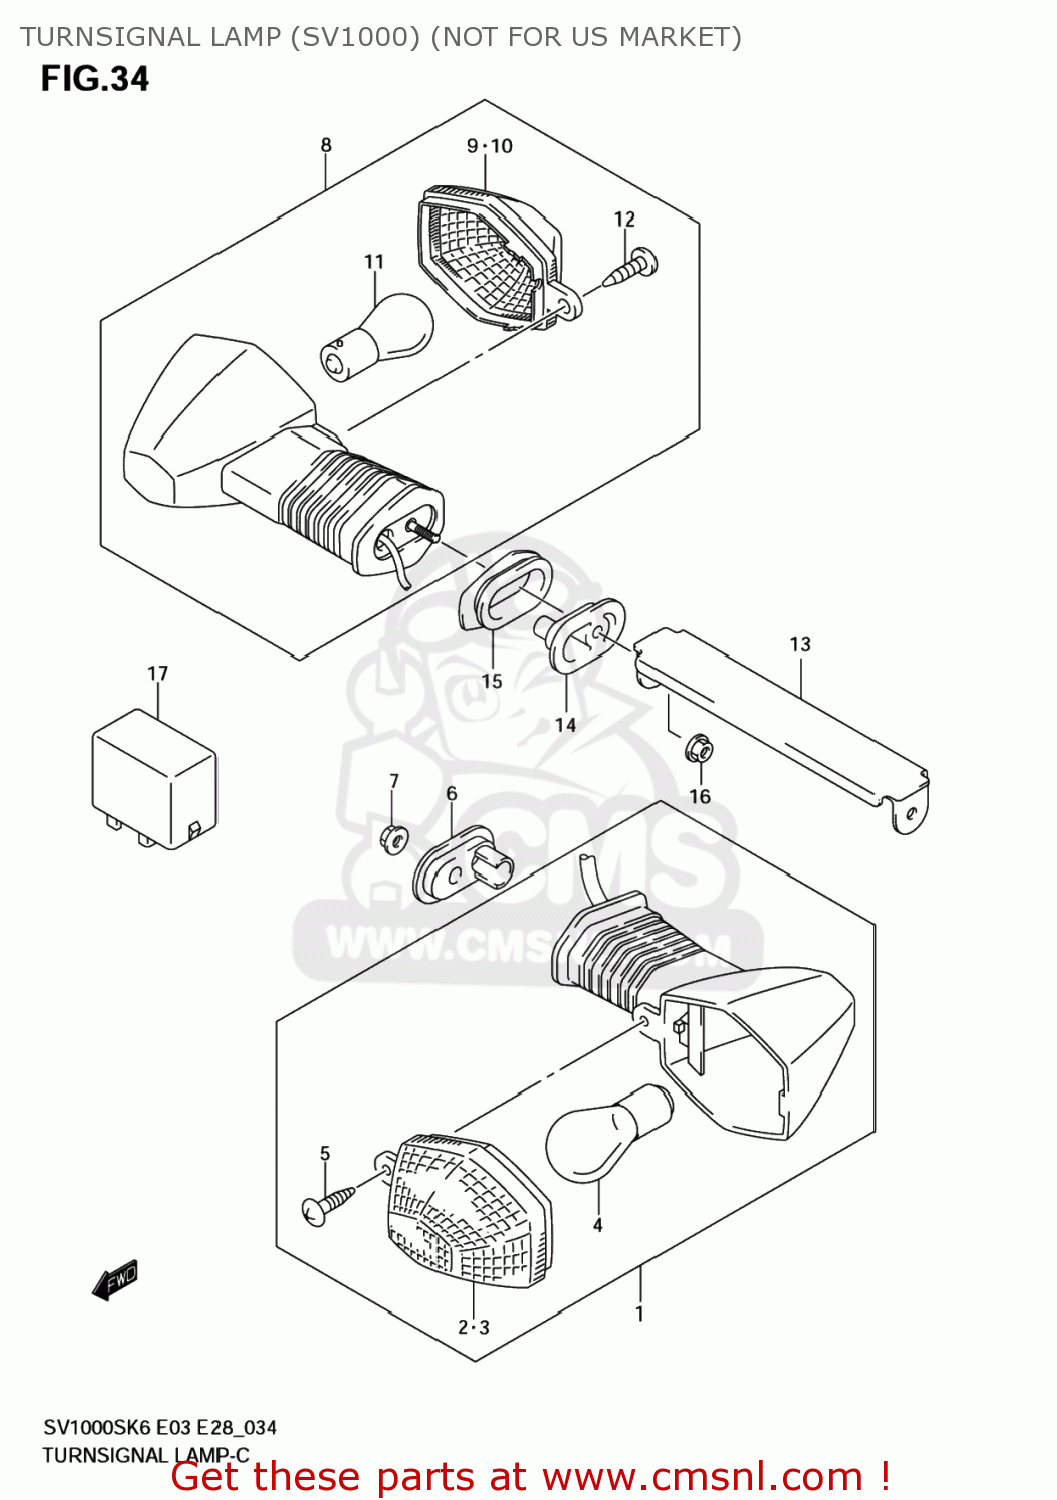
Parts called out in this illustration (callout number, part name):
1	LAMP ASSY,FR TURN,R
2	LENS
3	LENS
4	BULB(12V21W)
5	SCREW
6	PLATE,TURNSIGNAL LAMP
7	NUT
8	LAMP ASSY,RR TURNSIGNAL,R
9	LENS
10	LENS
11	BULB(12V21W)
12	SCREW
13	BRACKET,RR TURNSIGNAL
14	PLATE,RR TURN SIGNAL
15	CUSHION,RR
16	NUT
17	RELAY ASSY,TURNSIGNAL LAMP
